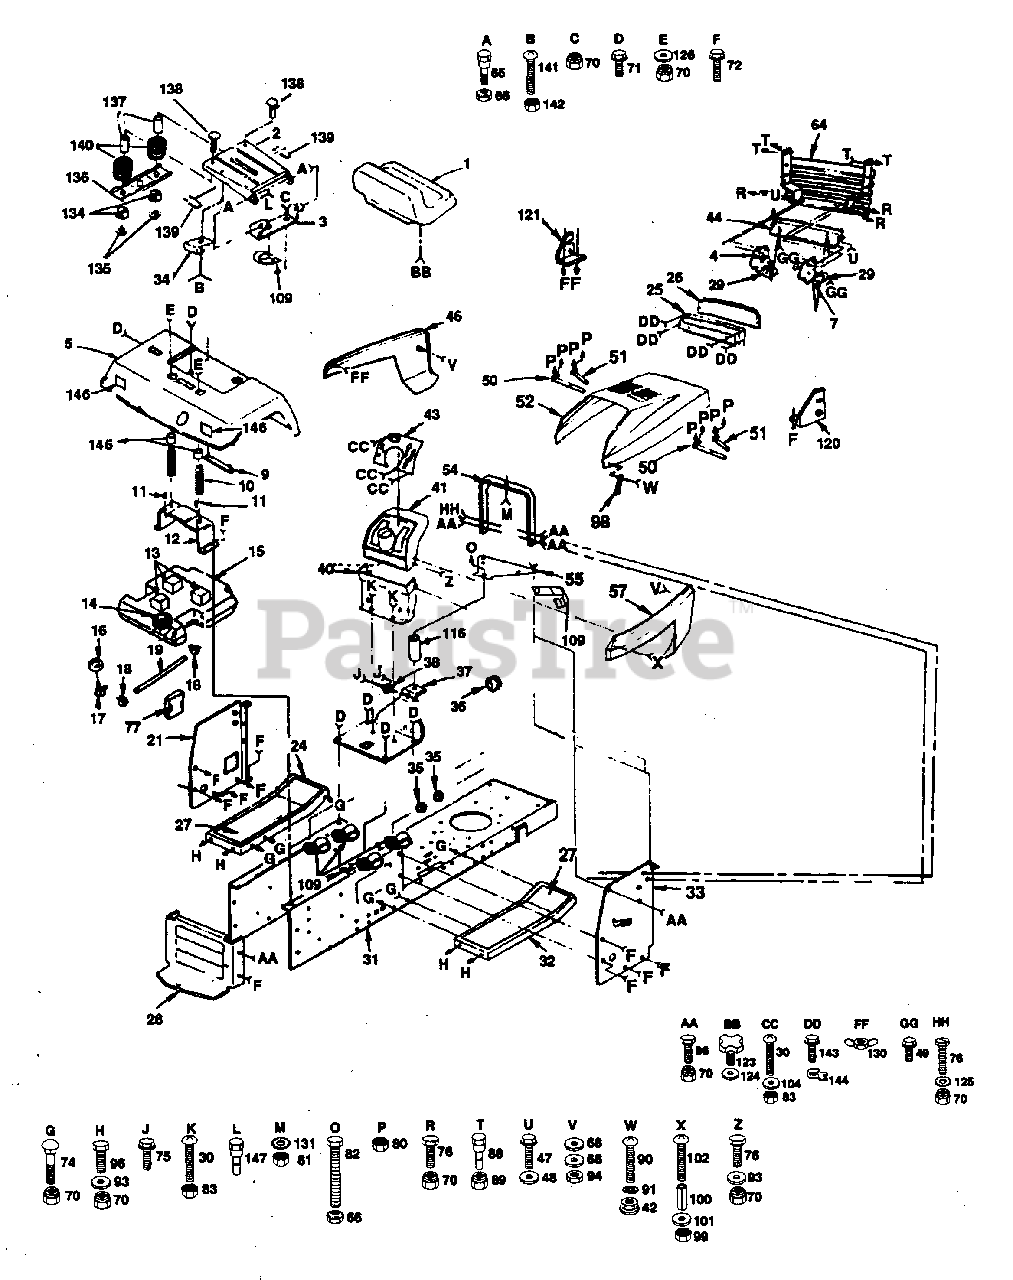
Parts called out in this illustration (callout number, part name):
1	Seat
3	Bracket, Pivot, Seat
4	Bracket, Asm. L.H. Pivot
7	Bracket, Asm. R.H. Pivot
9	Strap, Fender
10	Spring, Compression.Seat
12	Bracket, Fender
14	Cap, Fuel
16	Bushing
17	Stem, Tank, Fuel
19	Line, Fuel
21	Panel, Dash, L.H.
24	Footrest, L.H.
25	Bezel, Assembly
27	Pad, Footrest
29	Washer, 11/32 X 3/4 X 12 Ga.
30	Screw, Cr. Thd. 5/16-18 x 3/4
32	Footrest, R.H.
33	Panel, Dash, R.H.
34	Clip, Insulated
35	Grommet, Split
37	Saddle
38	Bushing, Steering
40	Dash Assembly, Lower
41	Dash
42	Nut, Weld
46	Panel, Side, L.H.
47	Screw, Hex Wsh. Thd. Cut 1/4-20 X 3/4
48	Washer 9/32 X 5/8 X 16 Ga.
49	Screw, Hex Wsh Thdrol 5/16-18 X 3/4
50	Strap Assembly, Hinge, Rear
51	Strap Assembly, Hinge, Front
54	Support, Dash
55	Plate, Support, Battery
57	Panel, Side R.H.
64	Grill Assembly
65	Bolt, Shoulder 5/16-18
66	Nut, Lock 5/16-18
68	Washer 9/32 X 3/4 X 16 Ga.
70	Nut, Crownlock 3/8-16
71	Screw, Hex Washer Thread Rolling 3/8-16 x 1/2
72	Screw, Hex Washer Thread Rolling 3/8-16 x 3/4
74	Bolt, Carriage 3/8-16 x 3/4
75	Screw, Hex Self Tapping #10-16 x 1/2
76	Bolt, Hex 3/8-16 x 1
77	Cover, Access
80	Nut, Hex Keps
81	Nut, Hex 1/4-20
82	Bolt, Hex 5/16-18 x 2
83	Nut, Keps 5/16-18
88	Bolt, Shoulder 1/4-20
89	Crownlock Nut 1/4-20
90	Screw, Pan Hd. Mach. #10-24 1/2
91	Washer, Lock #10
93	Washer 13/32 x 13/16 x 12 Ga.
94	Nut, Fin Hex 1/4-20 UNC
96	Bolt, Hex 3/8-16 x 3/4
99	Nut, Keps 10-24
100	Spacer, Split 10 x 3/4
101	Washer 7/32 x 1/2 x 18 Ga.
102	Screw, Mach. Cr. Pan 10-24 x 1-1/4
104	Washer 11/32 x 11/16 x 16 Ga.
109	Clip
120	Bracket Assembly, R.H.
121	Bracket Assembly, L.H.
123	Adjustment Knob
124	Washer 17/32 x 1-3/16 x 12 Ga.
125	Washer Lock 3/8 Ext. Tooth
126	Washer 13/32 x 1 x 14 Ga.
130	Wing Nut
131	Washer, 1/4 Ext. Tooth
134	Bushing, Snap .80
135	Nut, Hex, Large, Flange, Lock
136	Bracket, Switch Mount
137	Spacer, Split .28 x .88
138	Bolt, Carr. 1/4-20 x 1-3/8
140	Spring. Compression
141	Screw, Pan Hd. #10-32
142	Nut, Keps #10
143	Screw, Hex WH HD Tap #10-16 X 5/8
146	Reflector Taillight
147	Bolt, Shoulder 5/16-18 x .62
